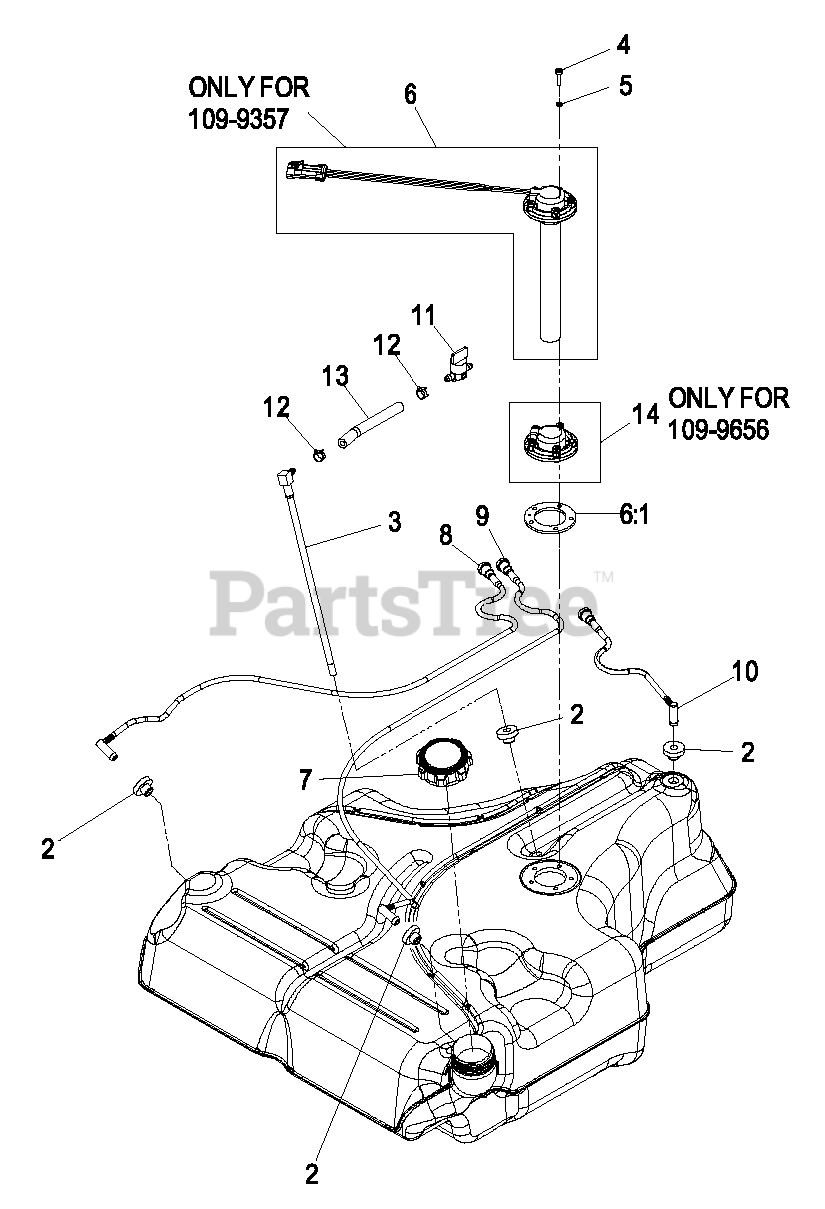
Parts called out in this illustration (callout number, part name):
2	BUSHING
4	SCREW-PAN
5	WASHER-LOCK
6:1	GASKET-SENDER, FUEL
11	VALVE-FUEL
12	CLAMP-HOSE
13	HOSE-FUEL
14	Cover, Plastic Fuel Tank (109-9656 Only)
